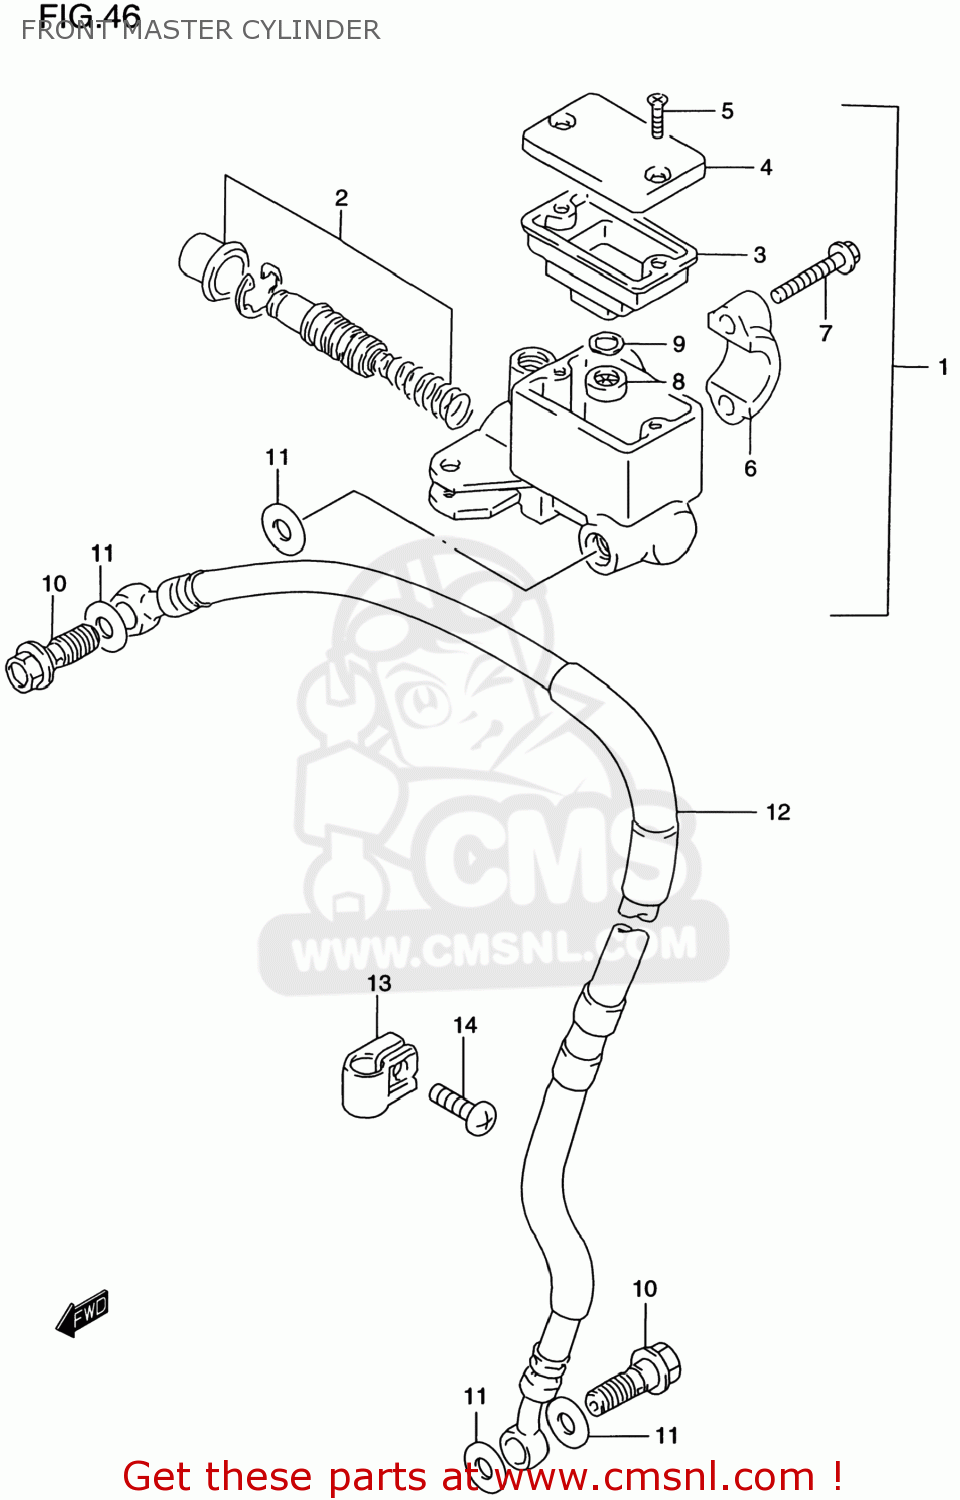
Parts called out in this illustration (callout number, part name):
1	CYLINDER ASSEMBLY,FRONT MASTER
2	PISTON/CUP SET
3	DIAPHRAGM
4	CAP
5	SCREW
6	HOLDER
7	BOLT(6X25)
8	SEPERATOR
9	PLATE
10	BOLT UNION
11	WASHER(10X15X1.5)
12	HOSE COMP,FRONT BRAKE
13	CLAMP,BRAKE HOSE
14	SCREW
